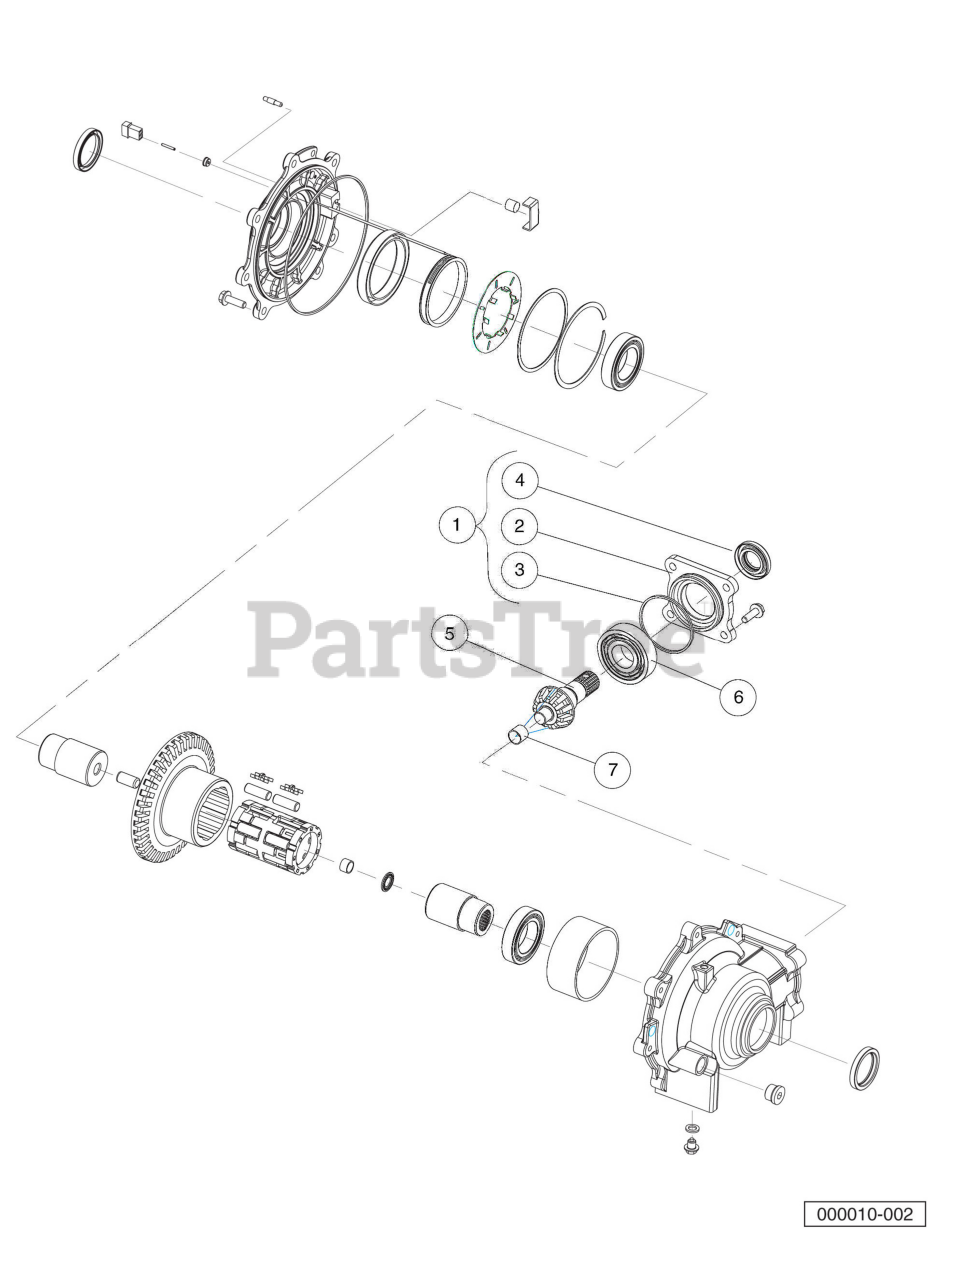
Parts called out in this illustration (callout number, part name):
1	Kit, Assy, Input Cover Plate
2	Cover, Input, Machined
3	O-Ring
4	Oil Seal, Triple-Lipped.
5	Shaft, Pinion, Machined
6	Bearing, Ball
7	Bushing, Plain 16 Id X 15 Wide
